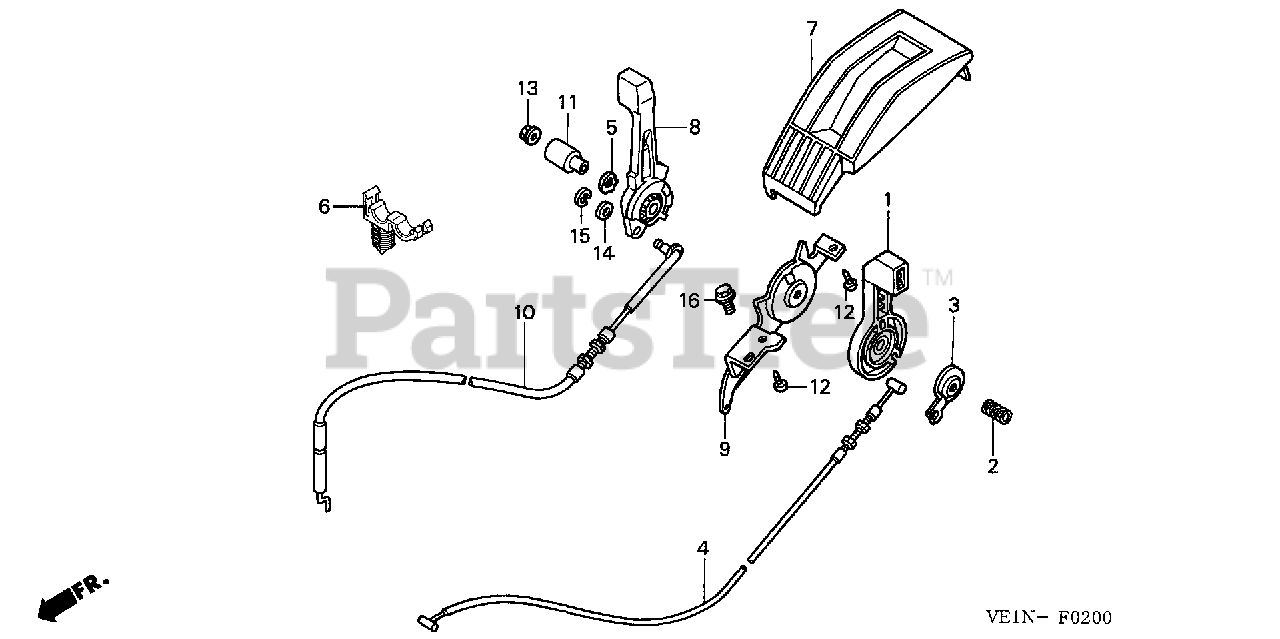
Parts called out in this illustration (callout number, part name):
1	LEVER, THROTTLE
2	SPRING, THROTTLE LEVER
3	SEAT, SPRING
4	CABLE, THROTTLE
5	WASHER, WAVE (11MM)
6	GUIDE, CABLE
7	COVER, CONTROL
8	LEVER, CHANGE
9	STOPPER, LEVER
10	CABLE, CHANGE
11	COLLAR, CHANGE LEVER
12	SCREW, TAPPING (5X12)
13	NUT, FLANGE (6MM)
14	WASHER, PLAIN (6MM)
15	E-RING (5MM)
16	BOLT, FLANGE (6X10)
